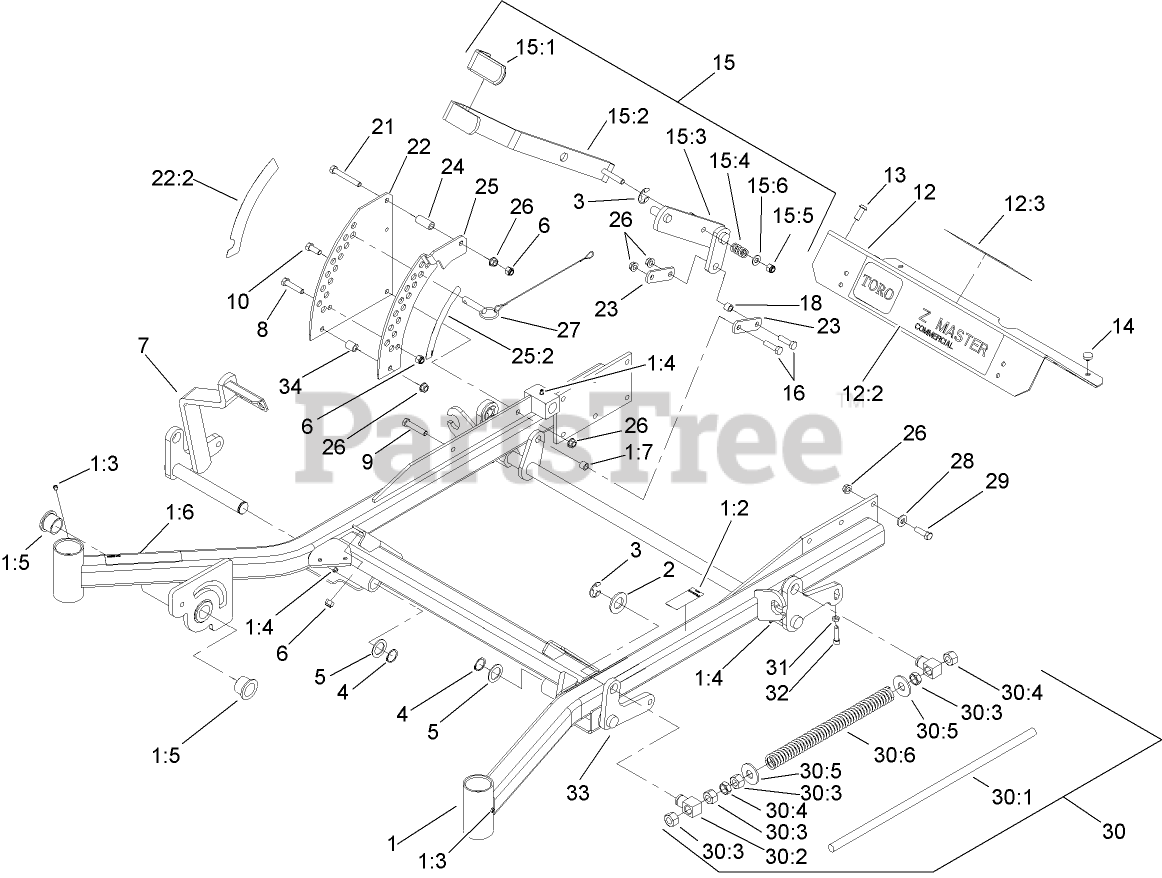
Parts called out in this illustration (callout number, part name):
1	Frame ASM
1:2	Decal-Brake, Parking
1:4	FITTING-GREASE
1:5	BUSHING
1:6	DECAL-WARNING
1:7	Bushing
2	WASHER-FLAT
3	RING-RETAINING, EXT
4	RING-RETAINING
5	WASHER-SPACER
6	NUT-LOCK, NI
7	LIFT-DECK, RH FRONT
8	SCREW-HH
9	SCREW-HH
10	SCREW-HH
12	FOOTREST
12:3	DECAL-WARNING
13	SCREW-HSBH
14	BUMPER
15	DECK LIFT HANDLE ASM
15:1	GRIP-LEVER, LIFT
15:2	LEVER-LIFT
15:3	ARM-LIFT, DECK
15:4	SPRING-COMPRESSION
15:5	NUT-LOCK, NI
15:6	WASHER-FLAT
16	SCREW-HH
18	Bushing
21	SCREW-HH
22	PLATE-DECK LIFT, OUTER
22:2	Decal-Height, Deck
23	ARM-LIFT, DECK
24	BUSHING-LEVER, LIFT
25	PLATE-DECK LIFT, INNER
25:2	Decal-Height, Deck
26	NUT-HHF, WHIZ
27	Hitch Pin ASM
28	WASHER-BELLEVILLE
29	SCREW-HH
30	FRONT FRAME SPRING ASM
30:1	ROD-LIFT, DECK
30:2	SWIVEL-DECK MOUNT, REAR
30:3	NUT-HEX
30:4	NUT-JAM
30:5	WASHER-FLAT
30:6	SPRING-SUPPORT, DECK
31	NUT-JAM
32	SCREW-HSH
33	LIFT-DECK, LH
34	BUSHING-LEVER, LIFT
